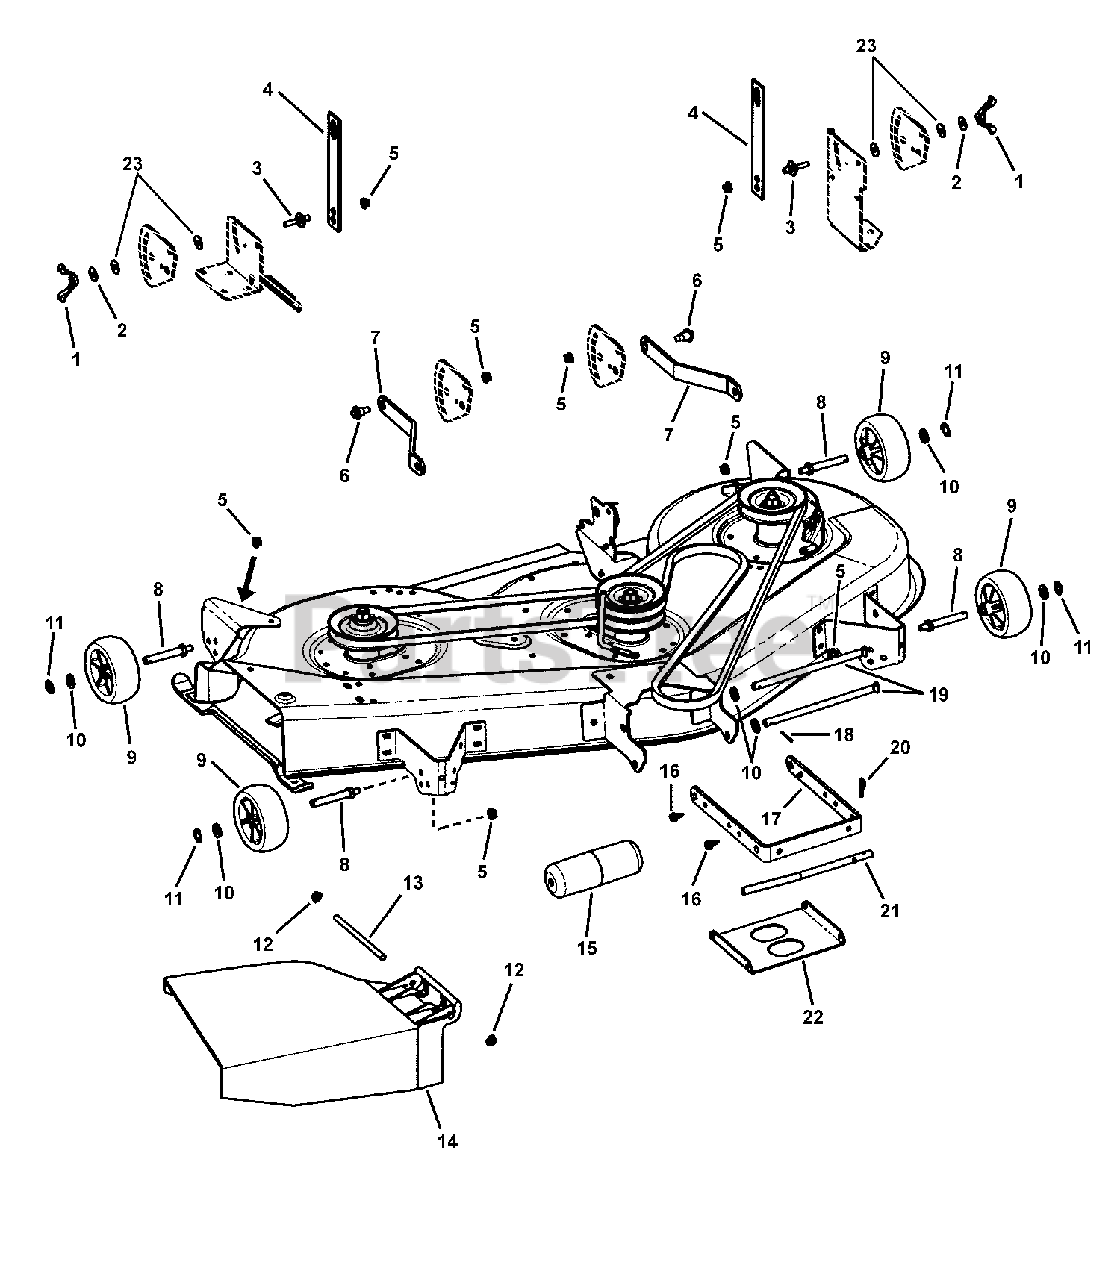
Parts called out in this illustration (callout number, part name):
1	WINGNUT (5/16-18 thread)
2	WASHER, Flat, 1.0 x .328 x 16 GA
3	PIN - Hanger 3/8-16 x 1-1/4"
4	LINK, Lift
5	NUT, 3/8-16 Hex Flange Lock, NC
6	SHOULDER BOLT, 3/8-16 x .600 OD x .95 L
7	BRACKET, Rear Suspension
8	BOLT, Axle, 3/8-16 x 3"
9	WHEEL, Gage
10	WASHER, Flat, 1.0OD x 0.550"
11	CLIP - Hair Pin
12	CAP, Push On (for .375 dia. Stud)
13	ROD, Deflector
14	DEFLECTOR, Chute
15	ROLLER
16	SCREW, 5/16-18 Hex Washer Self-Tap
17	BRACKET, Suspension, Front
18	COTTER PIN, 1/8 x 1-1/4"
19	ROD, Deck Suspension
20	HAIR PIN, .092 Dia.
21	ROD, Hanger
22	STIFFENER
23	WASHER
